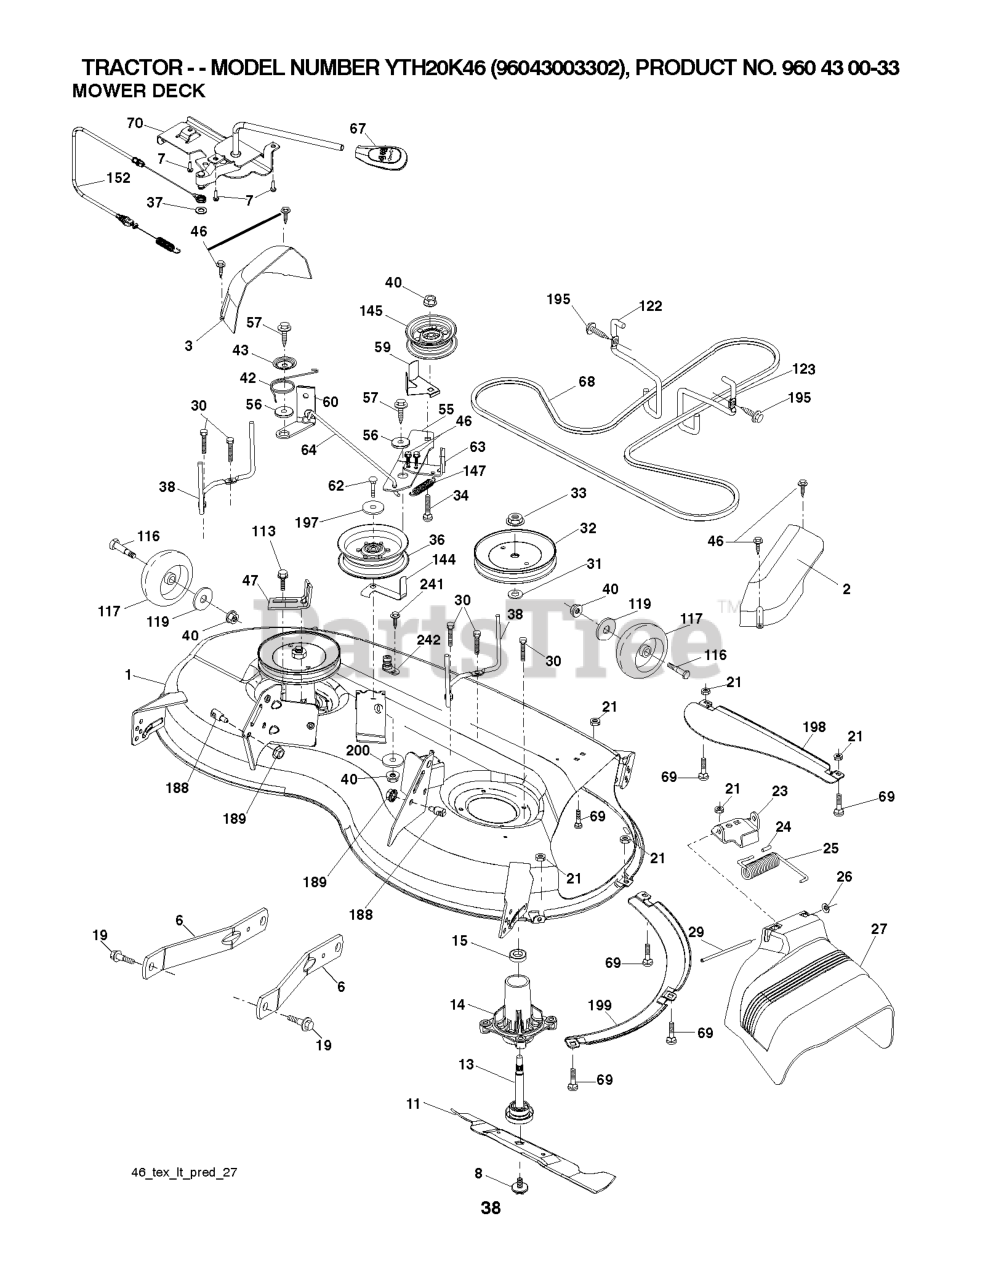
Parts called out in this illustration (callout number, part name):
1	DECK.WELDMENT.46"
2	COVER.MANDREL.RH.46"
3	COVER.MANDREL.LH.46"
6	ARM.SUSPENSION.MOWER.R
7	SCREW.#10 X 0.750.BOS
8	BOLT.WASHER.ASM.7/16-2
11	BLADE.MOWER.46".HI.LIFT
13	SHAFT.ASM.MDRL.N/GREASE.38
14	RP.HOUSING.MANDREL.4PT.
19	BOLT.SHOULDER
21	LOCKNUT
23	BRKT.DEFLECTOR.38"2005+
24	CAP-SLEEVE LT
25	SPRING.TORSION.DEFLECT
26	NUT PUSH M
27	SHIELD.DEFLECTOR.MOWER.46"BLAC
29	ROD.HINGE
30	SCREW, WASHER HEAD
31	WASHER.SPACER.MANDREL
32	PULLEY.MANDREL.5.438.PD
33	NUT.FLANGE.LOCK.TOP
34	BOLT.3/8-16X1.50
36	PULLEY.IDLER.2006
37	WASHER
38	KEEPER.BELT.LH.MANDREL
40	NUT LOCK FLG 3/8-16 UNC
42	SPRING.TORSION.BRAKE
43	SRPING.TORSION.RETAINE
46	SCREW.1/4-20X5/8
47	BRKT.CLUTCH.CABLE
56	SPACER.RETAINER
57	SCREW 3/8-16X1
59	GUARD, BELT
60	ARM BRAKE MOWER RH 38"
62	BOLT-HEX EAK
63	ARM BRAKE MOWER
64	LINKAGE BRAKE
67	HANDLE.CLUTCH.CABLE.LT
68	V-BELT
69	BOLT
70	CLUTCH.ASM.CABLE.HUSQ.TEX
113	BOLT.5/16HEX.WHS.HD
116	BOLT.SHOULDER.3/8-16X3-5/8.
117	RP WHEEL. GUAGE RALLY
119	WASHER
122	KEEPER BELT ENGINE LH
123	KEEPER BELT RH
144	KEEPER.BELT.MOWER
145	PULLEY.IDLER.48"PRIMARY
147	SPRING RETURN
152	CABLE CLUTCH MANUAL W/SPR.
188	STUD.FASTNER.W/ANTI-ROTATE
189	NUT LOCK HEX FLANGE 5/16-18
195	SCREW, 3/8-16X3/4
197	WASHER
198	BAFFLE CENTER FRONT
199	BAFFLE FRONT RH
200	WASHER.13/32 X 1 X 1/2.11GUARD
241	SCREW.TT.#10-32X.5.3/8.FLANGE
242	PORT.WASHOUT
